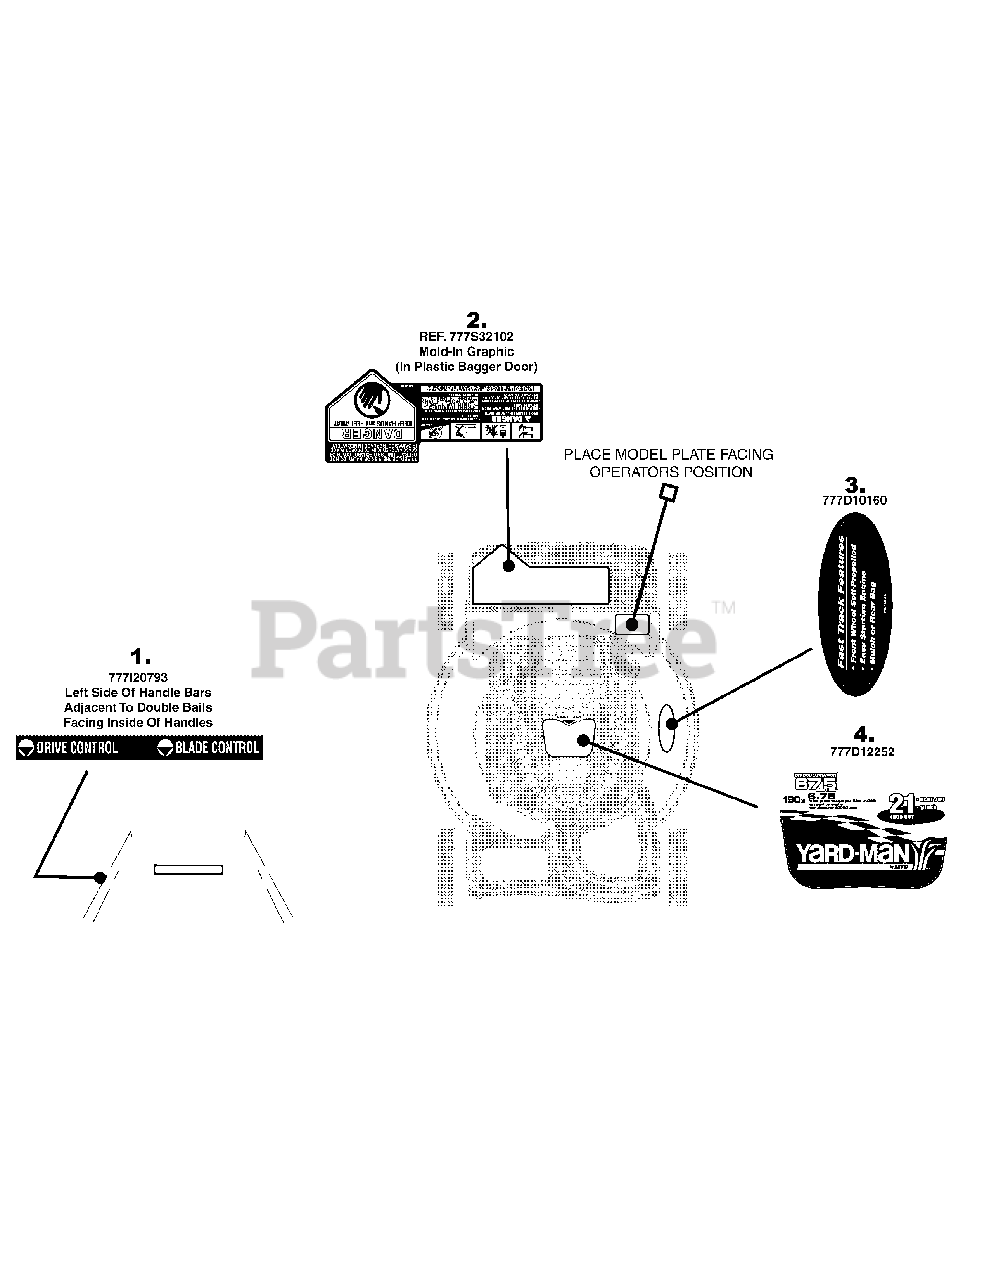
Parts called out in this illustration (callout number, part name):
1	LABEL-HANDLE
2	LABEL
3	LABEL-MOWER DECK YARD MAN FAST TRK
4	LABEL-MOWER SHROUD YARD MAN 2 IN 1
